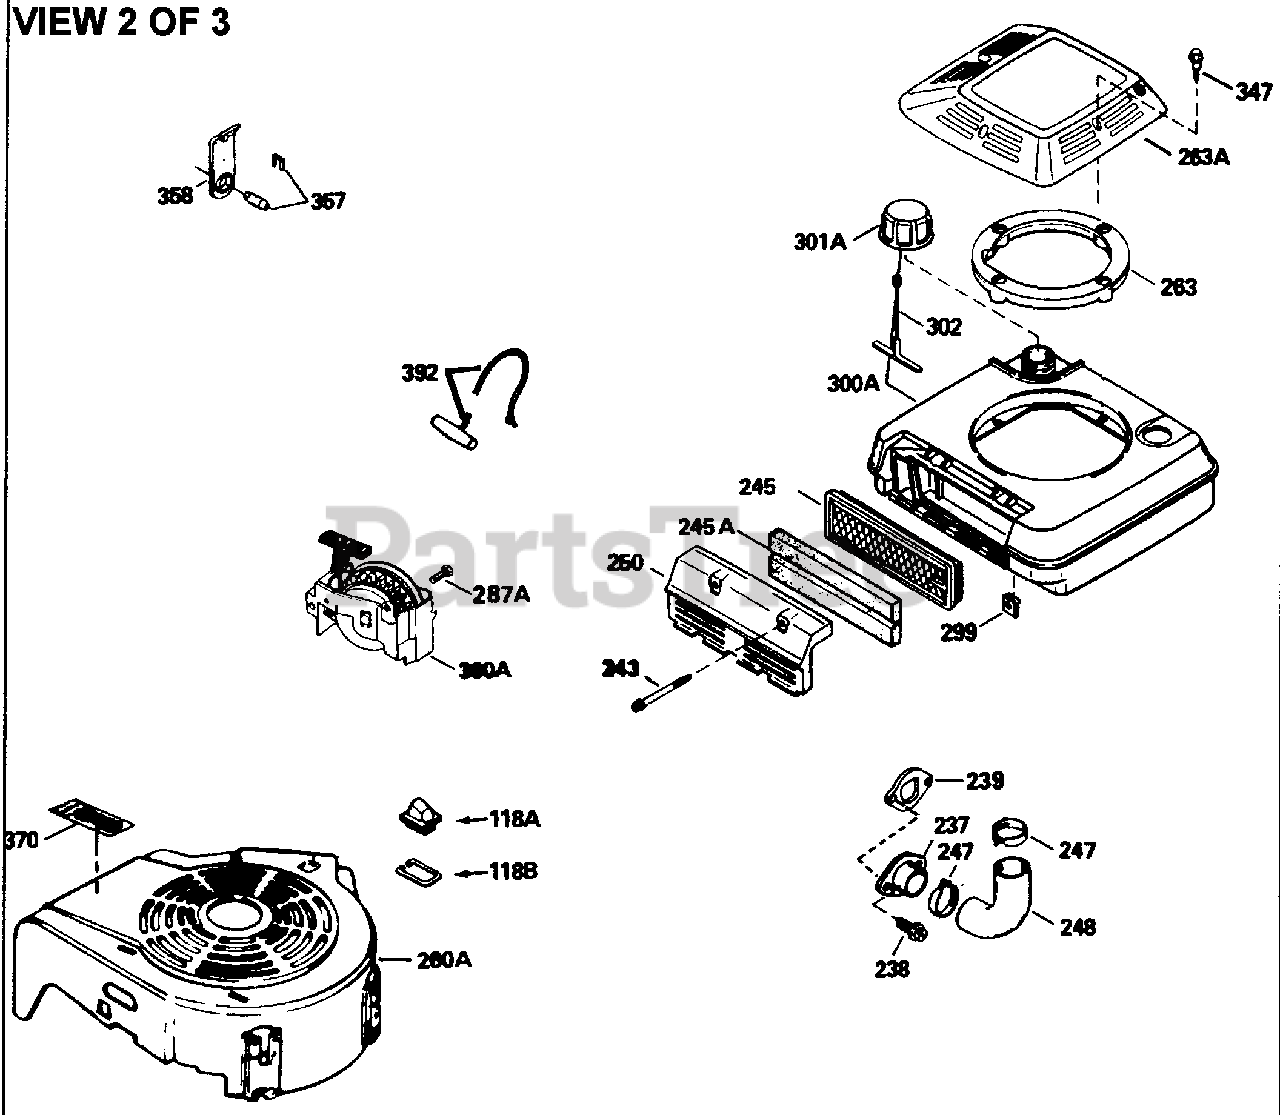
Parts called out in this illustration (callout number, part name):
55A	Shaft, P.T.O.
118	Rope Guide Kit (Use as required)
237	Adapter, Air cleaner
238	Screw, 10-32 x 7/16"
239A	Air Filter Gasket
245F	Air Filter (also available in Package d Part #740013B)
246E	Filter, Pre-air (Use as required)
247C	Clamp, Air cleaner tube
248	Tube, Air cleaner
250E	Cover, Air cleaner
260B	Housing, Blower
263	Ring, Shroud
287A	Pop Rivet (3/16" Dia.) Purchase local ly
287A	Screw, 10-24 x 3/8" (Use as required)
287B	Screw, 8-32 x 1/2"
299	Clip, "U" type nut, 10-32
300C	Shroud & Tank Ass'y. Incl. 299 & 301 A
301A	Fuel Cap (Red)
347	Screw, 10-32 x 27/32"
370H	Decal, Instruction (Optional)
370J	Decal, Instruction (Optional)
390B	Rewind Starter Refer to Division 5, S ection C, page 34 or Fiche 8A, Grid G -5 for breakdown
425	Starter Muff Kit (Incl. 370J,426,427) Opt.
426	Starter Air Cleaner (Optional)
427	Starter Air Cleaner Bracket Optional
436	Stator Plate Ass'y. Incl. 377,378,437 , 442-448
437	Spring, Breaker box cover
438	Cover, Dust
439	Gasket, Stator cover
440	Cam, Breaker
443	Nut, 8-32
444	Breaker Fastening Screw & Washer
445	Condenser Fastening Screw
446	Terminal, Ground
